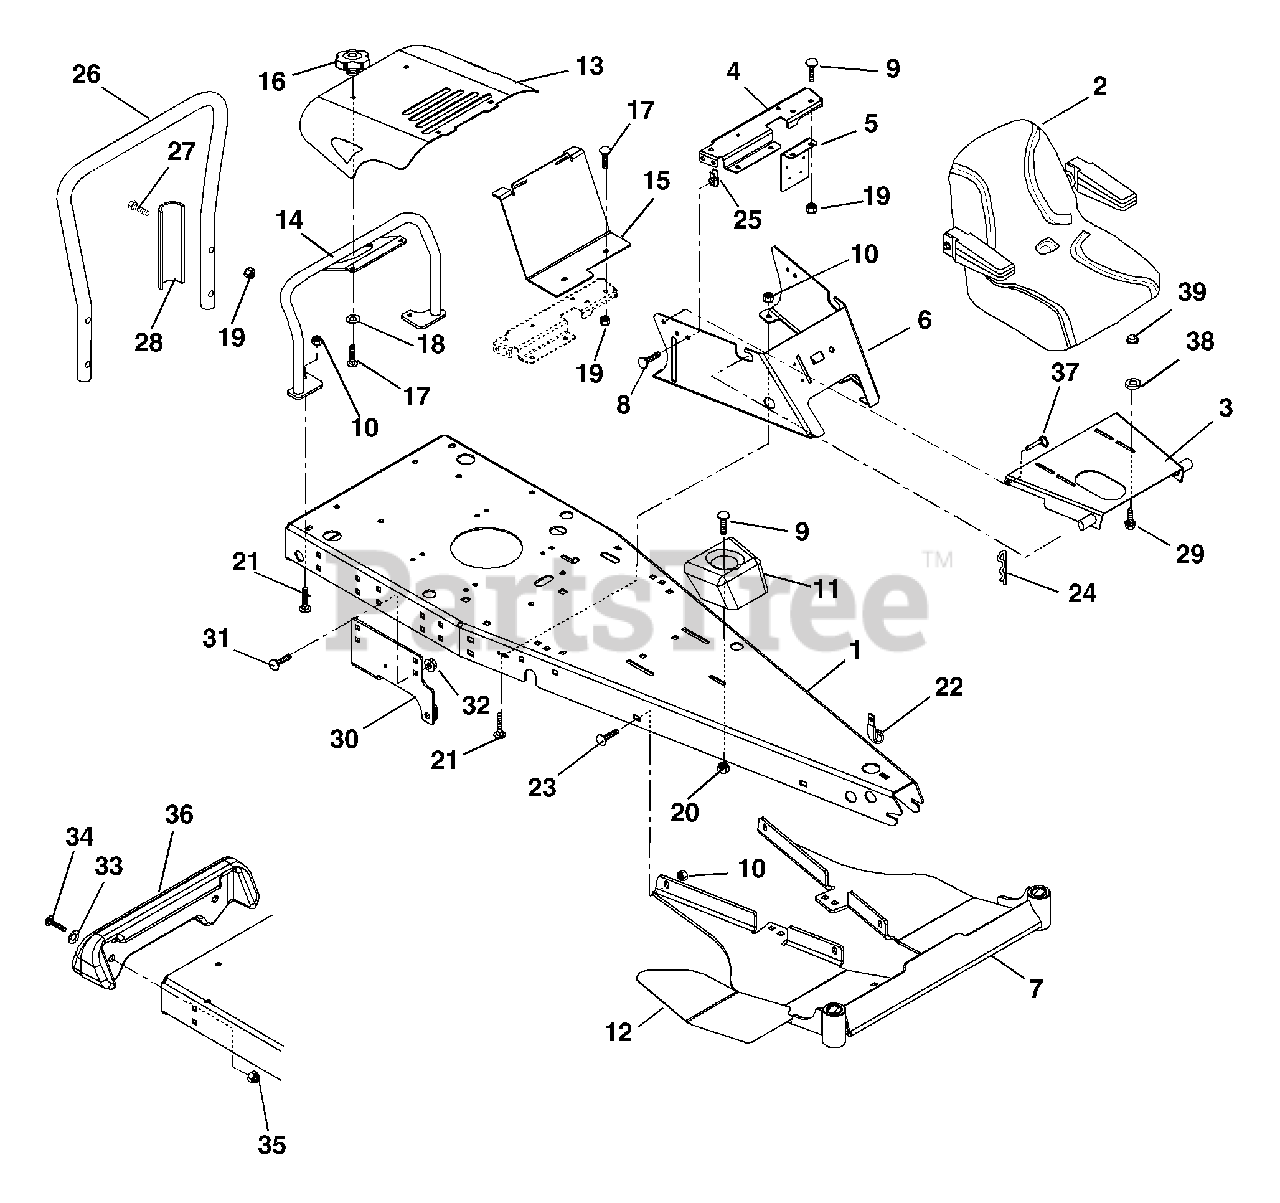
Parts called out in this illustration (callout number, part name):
2	Seat, TS2500 Michigan with Arms
3	Weldment, Seat Plate
4	Reforcement, Seat Support
5	Panel, Solenoid Mounting
6	Seat Support
7	Weldment-Footrest
8	Bolt-Serrated Hex Flange Washer Head .25-20 x .75
9	Bolt, Round Head Square Neck .31-18 x .75 Grade 5
10	Nut, Locking Top Flange .38-16
11	Cupholder
12	Grip, Footrest Left Hand
12	Grip, Footrest Right Hand
13	Engine-Hood (064)
14	Weldment Tube (064)
15	Bracket, Hood Support (064)
16	Knob, Clamping .31-18 Nyloc (064)
17	Bolt-Round Head Square Neck .31-18 x 1.00 (064)
18	Nut-Push .312 (064)
19	Nut-Locking-Top-Flange .31-18
20	Nut-Spin Lock-Flange .312-18
21	Bolt-Round Head Square Neck .38-16 x .75 Grade 5
22	J-Clamp
23	Bolt-Round Head Square Neck .38-16 x 1.00 Grade 5
24	Pin-Hair-External .12 x .31 x 2.37
25	Nut-Retainer .25-20 x .56
26	ube (060, 062)
27	Bolt, Hex .31-18 x 1.50 Grade 5 (060, 062)
28	Brace (060, 062)
29	Bolt-Serrated Hex Flange Washer Head .31-18 x 1
30	Bracket, Transmission - Right Hand
30	Bracket, Transmission - Left Hand
31	Bolt, Round Head Square Neck .38-16 x .75 Grade 5
32	Nut, Locking Top Flange .38-16
33	Washer-Flat-Steel .438 x 1.00 x .083
34	Bolt-Hex .38-16 x 1.75 Grade 5
35	Nut-Locking-Top-Flange .38-16
36	Weight
37	Pin, Detent with Ring .25 x 1.00
39	Nut, Push .312
